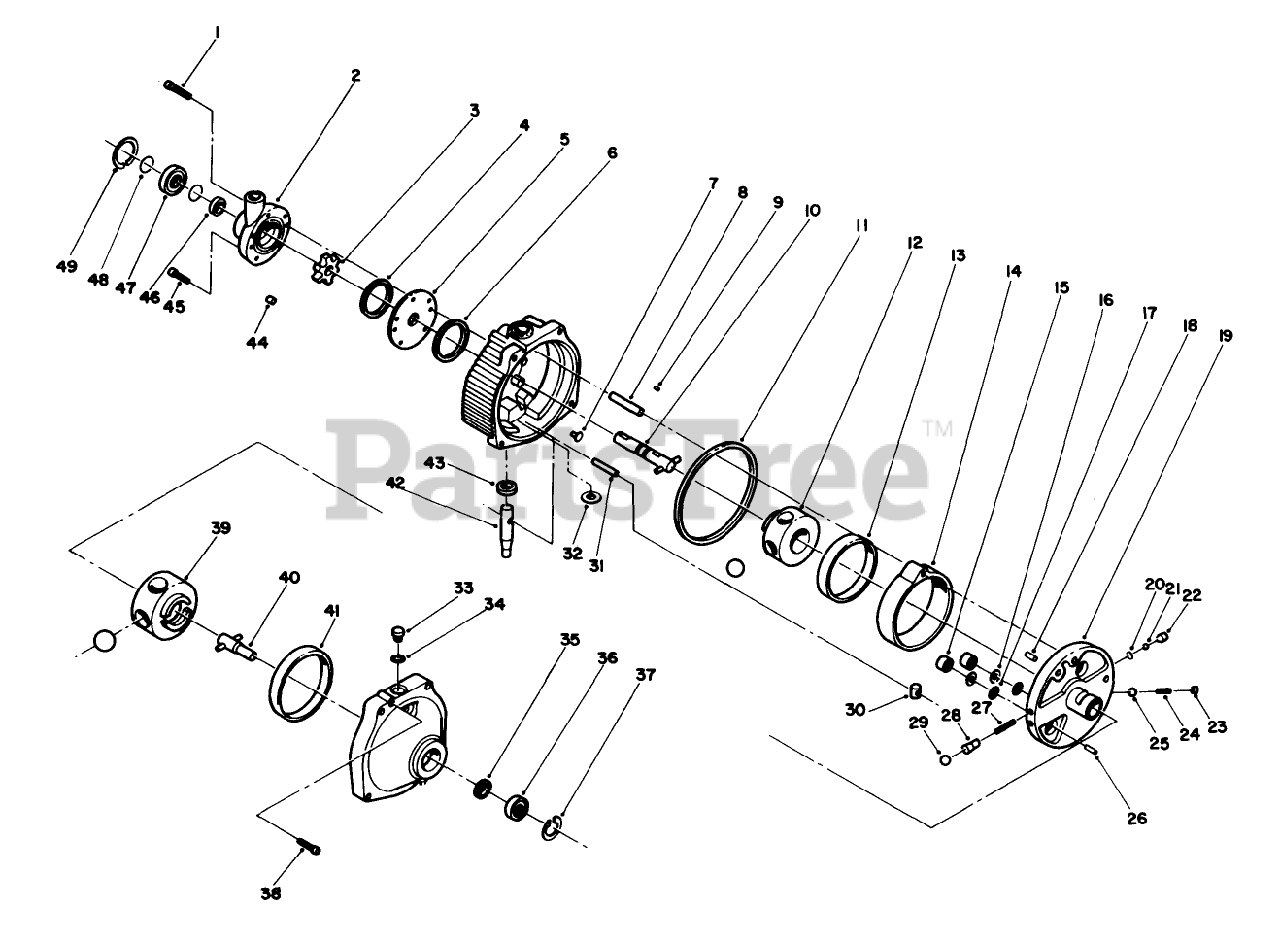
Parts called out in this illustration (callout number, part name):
1	CAPSCREW
2	Charge Pump (Incl. Ref. #1)
3	CARRIER
5	PLATE
7	BUTTON
10	SHAFT
12	ROTOR
13	Pump Race
14	Cam Ring Assy. (Incl. Ref. #13)
15	PISTON
17	O-RING
19	Pintle Assembly (Incl. Ref. #15-18, 20, 22-26, 27-29)
24	SPRING
27	SPRING
30	INSERT
31	Dowel
32	Control Shaft Washer
33	"O" Ring Plug Sub-Assembly (Incl. Ref. #34)
34	O-RING
35	Oil Seal
36	Bearing
38	Socket Head Capscrew
39	ROTOR
40	SHAFT
42	Control Shaft Kit (Incl. Ref. #31 & 32)
43	SEAL-OIL
45	SCREW-HH
46	SEAL-OIL
47	BEARING
49	RING
